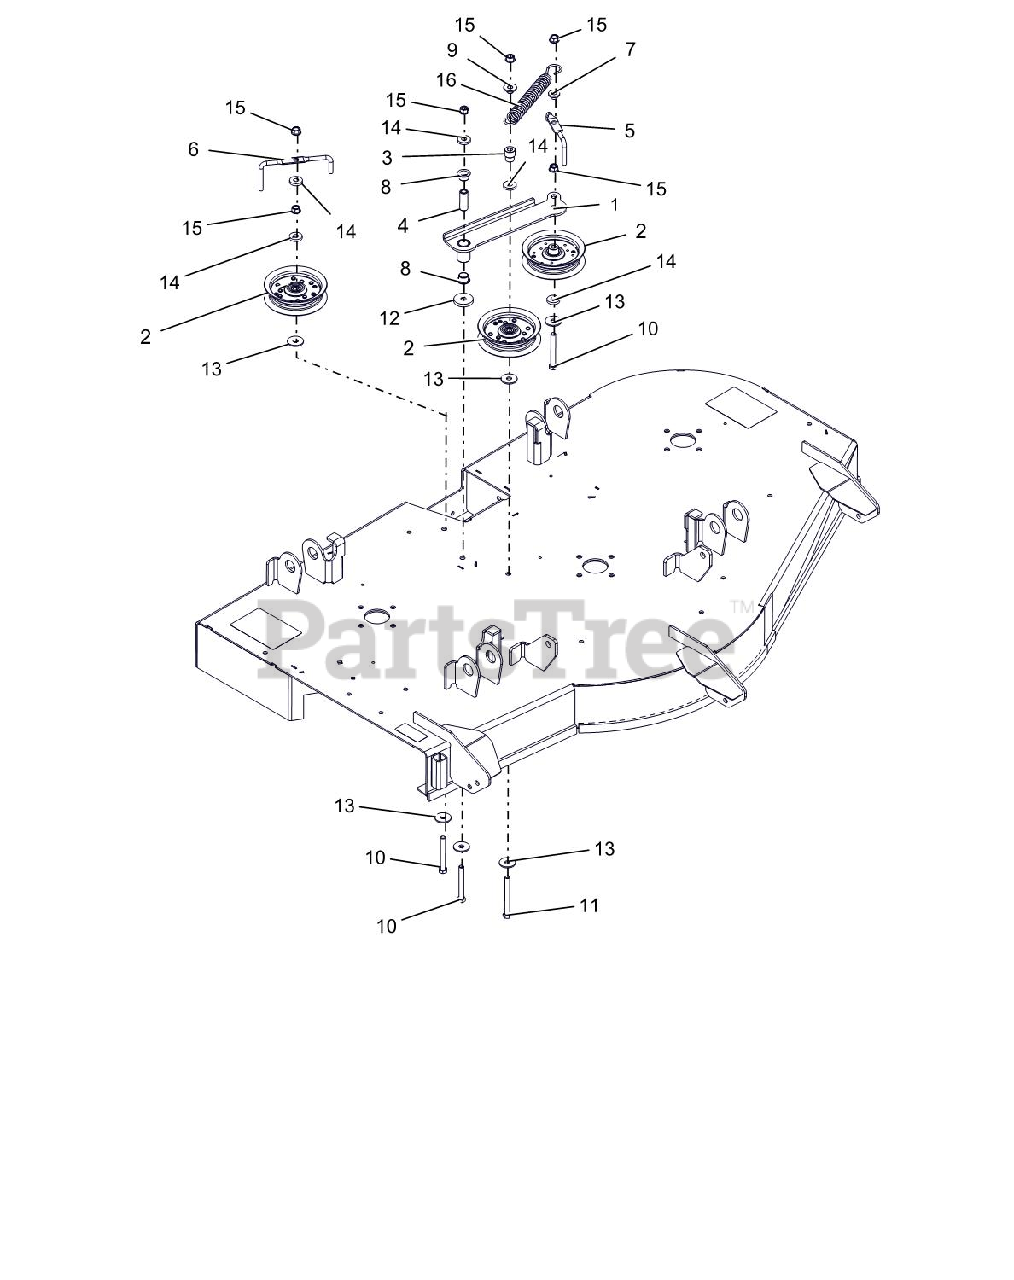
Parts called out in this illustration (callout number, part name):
1	WLDMT, IDLER ARM-52"
2	ASM, IDLER 4"
3	BUSHING, IDLER (P/M)
4	SPACER, .375IDX.625ODX1.66 PM
5	WIREFORM, BELT FINGER
6	BELT FINGER
7	BSHG-FLG .385X.500X.875X.406
8	BSHG-FLG, .625X.750X.500X1.00
9	BSHG-FLG .385X.500X.875X.31
10	BLT-HEX .38-16X3.00 GR5 FTH YZ
11	@BLT-HEX .38-16X3.50 GR5 YWZC
12	WSHR,FLT STL.406X1.50X.245YWZC
13	@WSHR-FL-STL .406X1.25X.10 ZC
14	WSHR-FL-STL .406X1.00X.188 YWZ
15	@NUT-LK-TOP-FLG .38-16 YWZC
16	SG-TENS .135X.98X6.0 WLD 62
